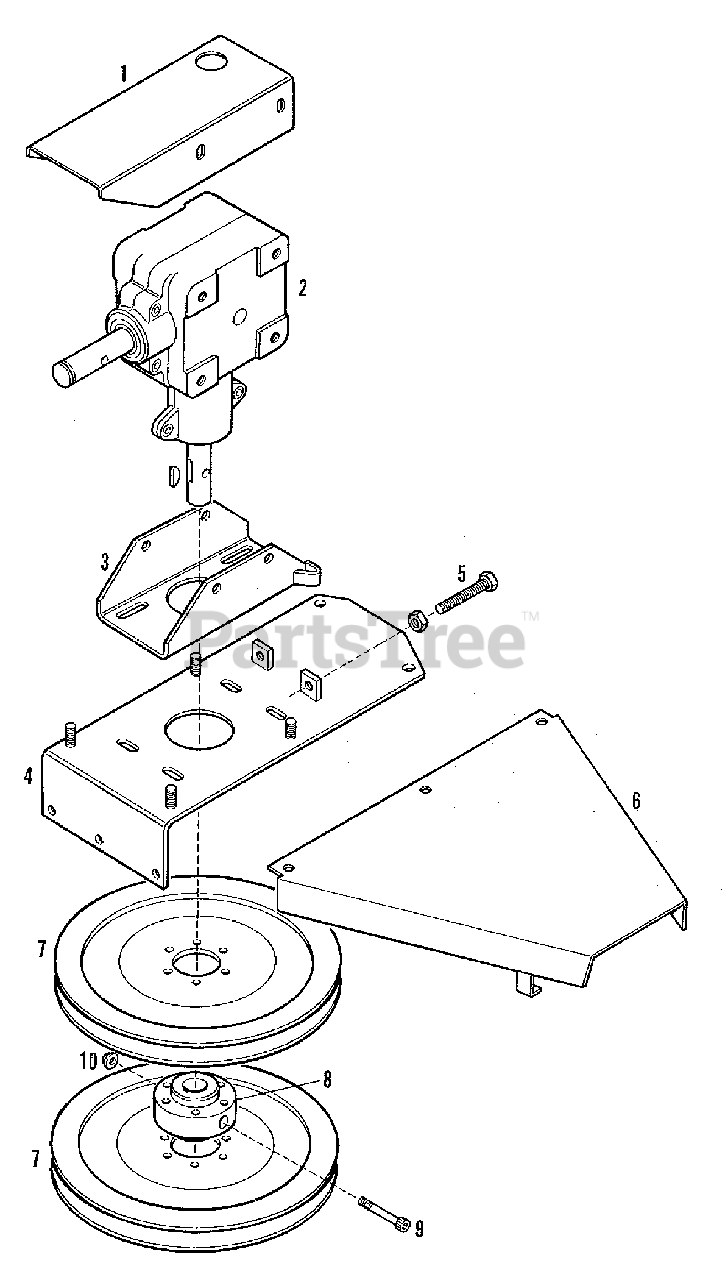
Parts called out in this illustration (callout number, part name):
1	SHIELD, Universal
1	CAPSCREW, 3/8NC x 1
1	WASHER, Plain, 13/32 x 13/16 x 1/16
1	LOCKWASHER, 3/8
2	GEARBOX ASSEMBLY
2	KEY, Woodruff, 3/16 x 3/4 x 5/16
3	BRACKET, Gearbox
3	CAPSCREW, 3/8NC x 1
3	LOCKWASHER, 3/8
4	PLATE, Gearbox
4	CAPSCREW, Serrated Head, 3/8NC x 1
4	BOLT, Carriage, 3/8NC x 1
4	WASHER, Plain, 13/32 x 13/16 x 1/16
4	LOCKWASHER, 3/8
5	CAPSCREW, 3/8NC x 2-1/2, Full Thread
6	SHIELD, Belt
6	CAPSCREW, Serrated Head, 3/8NC x 1
6	LOCKWASHER, 3/8
7	SHEAVE, 12" O.D.
7	CAPSCREW, 5/16NC x 1-3/4
7	LOCKWASHER, 5/16
7	NUT, 5/16NC
8	HUB, Sheave
8	CAPSCREW, Hex Socket Head, 3/8NC x 2-1/2, Gr. 8
8	NUT, Lock, Flange, 3/8NC
